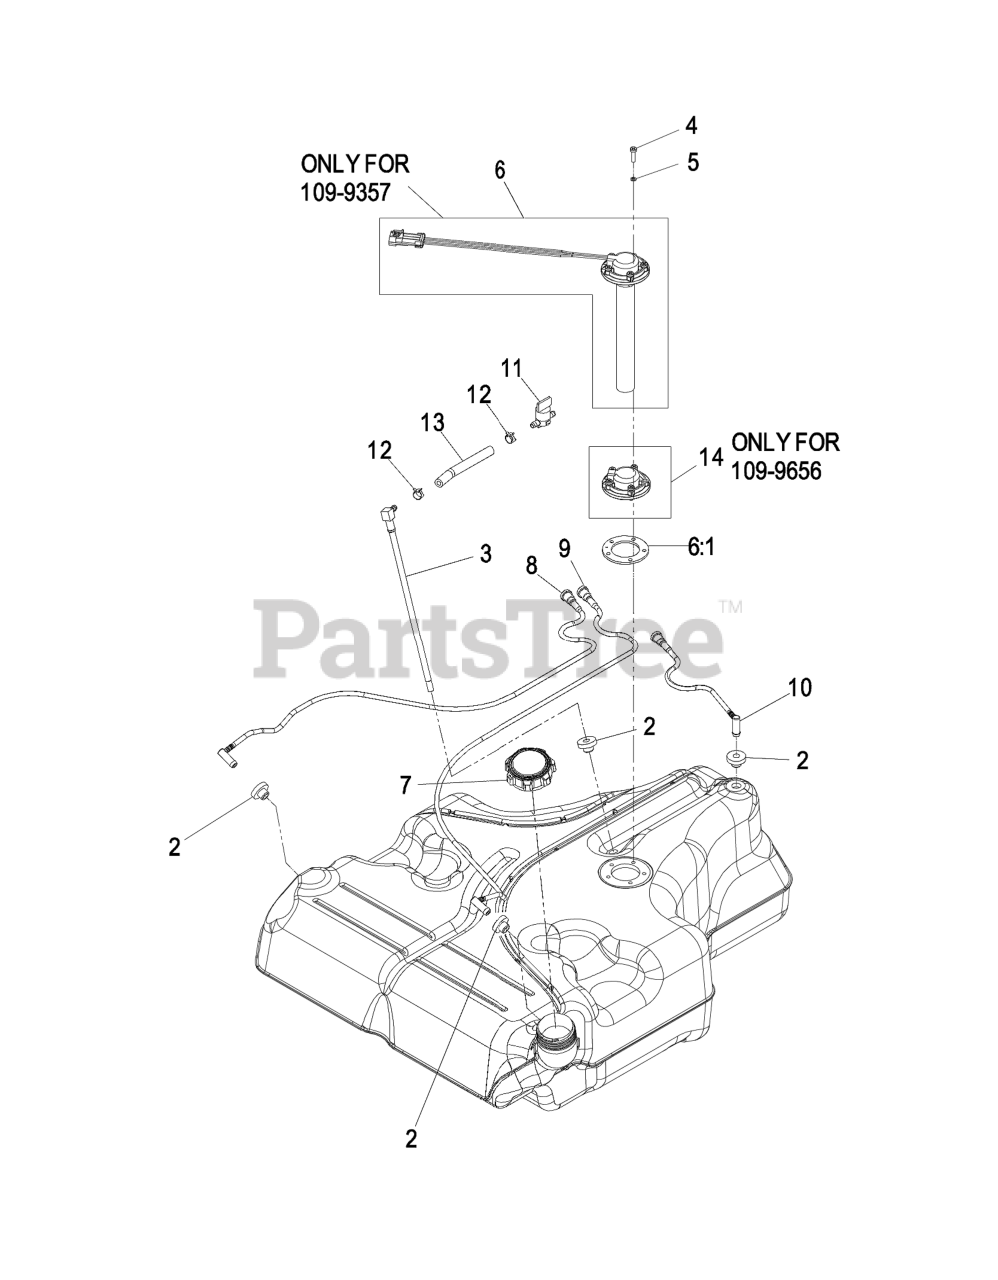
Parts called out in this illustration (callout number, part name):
2	BUSHING
4	SCREW-PAN
5	WASHER-LOCK
6:1	GASKET-SENDER, FUEL
11	VALVE-FUEL
12	CLAMP-HOSE
13	HOSE-FUEL
14	Cover, Plastic Fuel Tank (109-9656 only)
